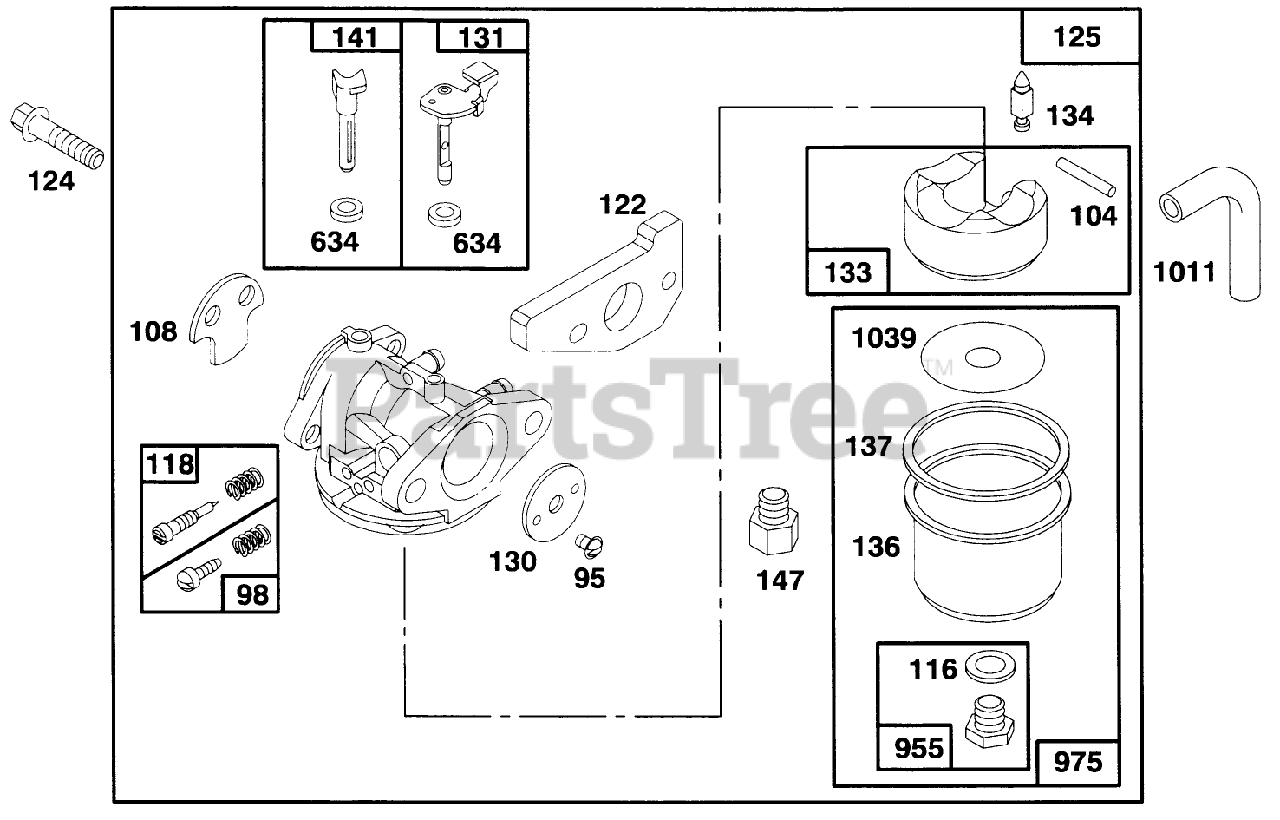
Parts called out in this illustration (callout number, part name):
98	IDLE ADJUSTING SCREW
116	SEALING GASKET
118	VALVE KIT - NEEDLE
122	ADAPTER ASSEMBLY
124	HEX HEAD SCREW
130	THROTTLE VALVE
133	FLOAT-CARBURETOR
134	VALVE-FLOAT
137	FLOAT BOWL GASKET
147	JET ADAPTER
1011	VENT TUBE
1039	FLOAT LIMITER
